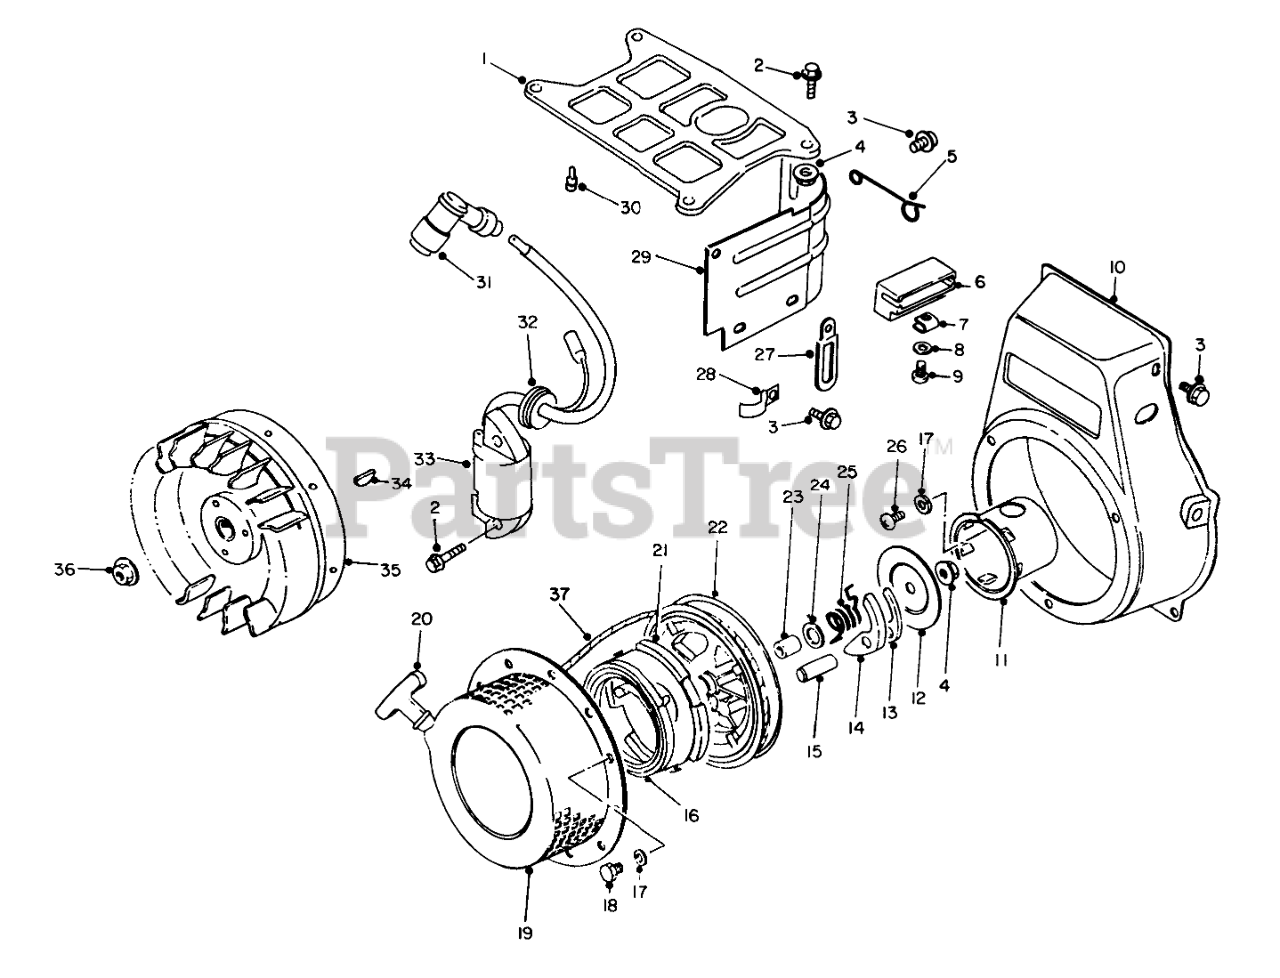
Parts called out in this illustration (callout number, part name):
1	Cowling-Upper
5	CLAMP
6	Holder-Lead Connector
8	Washer
10	COVER
11	Pulley-Starter
12	Plate
13	Ratchet
14	Ratchet
16	SPRING
17	LOCKWASHER
19	Starter Assembly (Incl. Ref. #4, 12-18 & 20-25)
20	Grip Assembly
21	SPRING CASE
23	Cover
24	Plate-Slide
25	Spring
26	Screw
27	CLAMP
28	Clamp
29	COWLING
30	Cushion
31	SPARK PLUG CAP
32	Grommet
33	STATOR
35	ROTOR ASM
